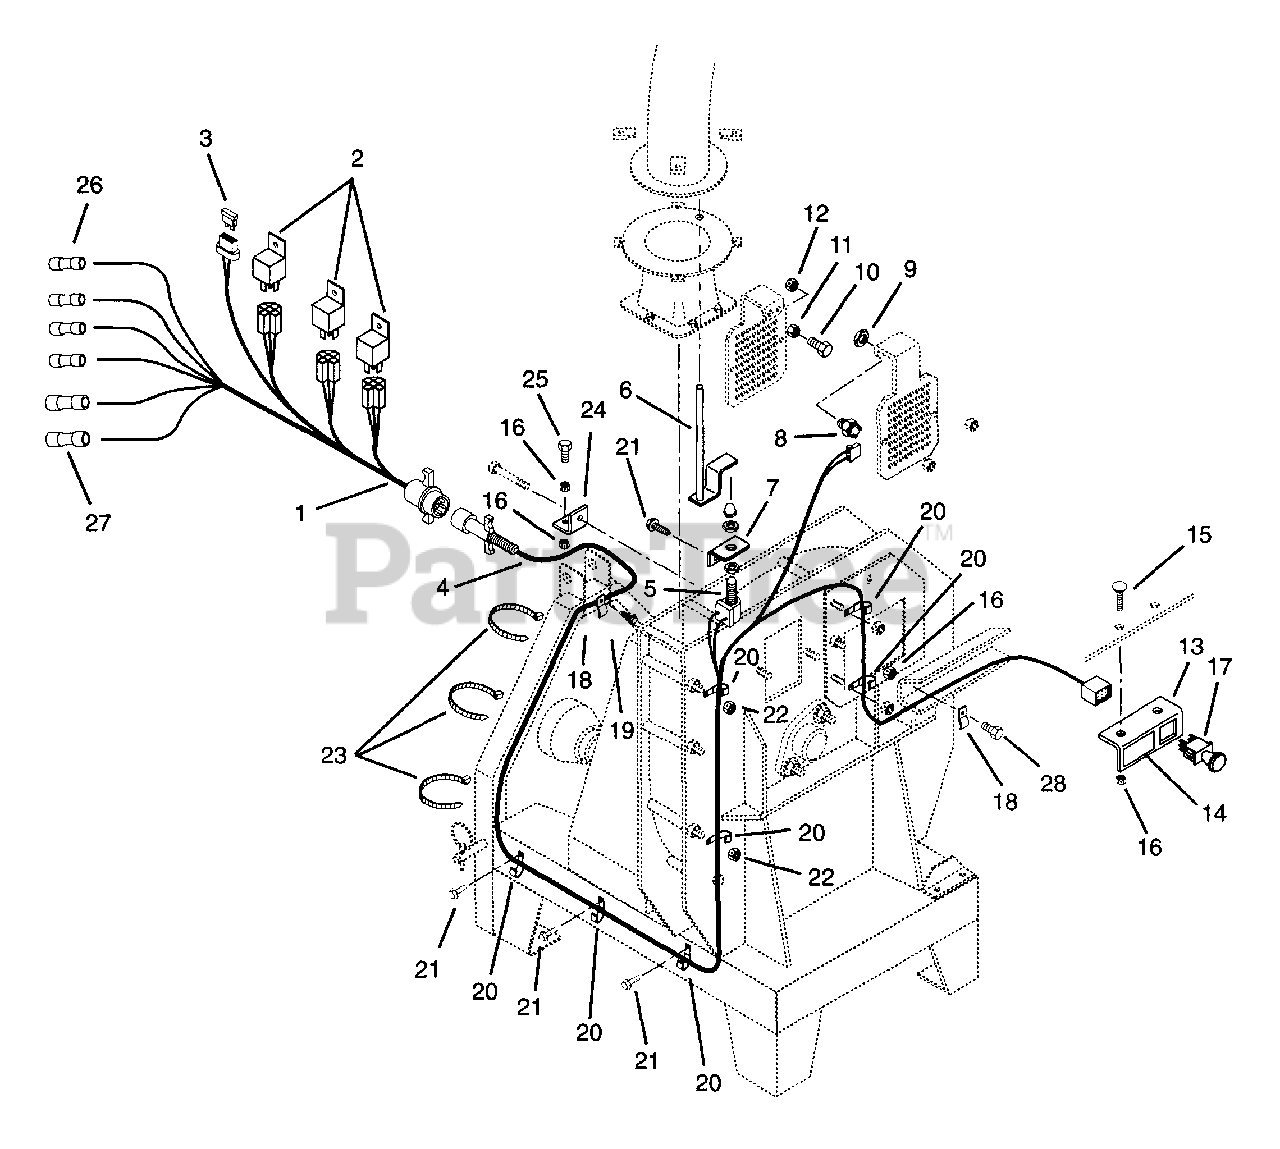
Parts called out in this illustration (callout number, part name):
1	Harness-Wiring PTO6 - Tractor
2	Relay
3	Fuse-25 Amp
4	Harness-Wiring PTO6 - Chipper
5	Switch-Sealed Safety
6	Actuator-Switch
7	Bracket-Switch and Relay
8	Switch, Safety
9	Nut, Stamped .56-18
10	Bolt-Hex .31-18 x 1.00 Grade 5
11	Nut-Hex .31-18
12	Nut-Locking-Center .31-18
13	Bracket-Stop Switch
14	Decal, Emergency Stop
15	Bolt, Round Head Square Neck .25-20 x .50 Grade 5
16	Nut-Locking-Center .25-20
17	Switch, Emergency Stop
19	Screw-Tapping .25-20 x .50 Hex Washer Head
21	Screw-Tapping .38-13 x .50 Hex Washer Head
22	Nut-Locking-Center .38-16
23	Tie Wrap
24	L-Bracket
25	Bolt-Hex .25-20 x 1.50
26	Butt Connector 16-14
27	Butt Connector 12-10 Gauge
28	Bolt-Hex .25-20 x .75 Grade 5
